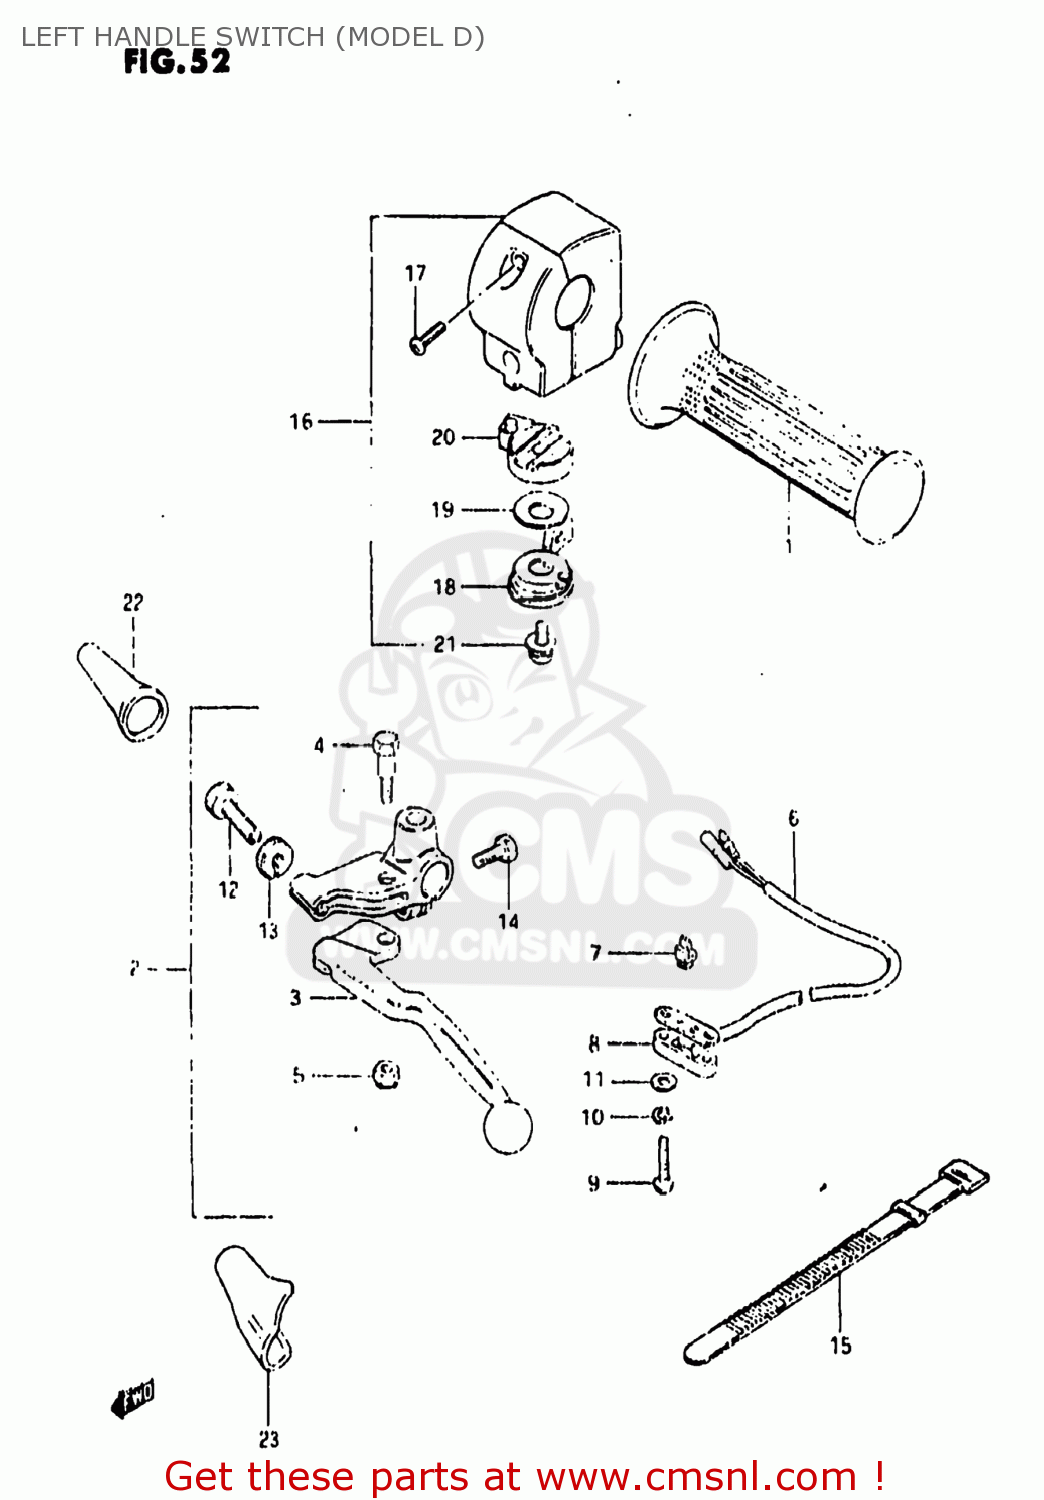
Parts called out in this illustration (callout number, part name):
1	GRIP,LEFT
2	LEVER ASSEMBLY
3	LEVER,CLUTCH
4	BOLT,LEVER
5	NUT 6MM
6	WIRE HARNESS,CLUTCH SWITCH
7	CONTACT,SWITCH
8	COVER,FR BK TERMINAL BASE
9	SCREW
10	LOCK WASHER
11	WASHER
12	ADJUSTER,CABLE
13	NUT,CABLE ADJUSTER
14	BOLT,CLUTCH LEVER HOLDER
15	CLAMP(L:120)
16	SWITCH ASSEMBLY,HANDLE,LEFT
17	SCREW
18	LEVER,STARTER
19	WASHER,ADJUSTER
20	BODY,STARTER LEVER
21	SCREW,CHOKE LE
22	BOOT,CLUTCH CABLE
23	COVER,CLUTCH LEVER
